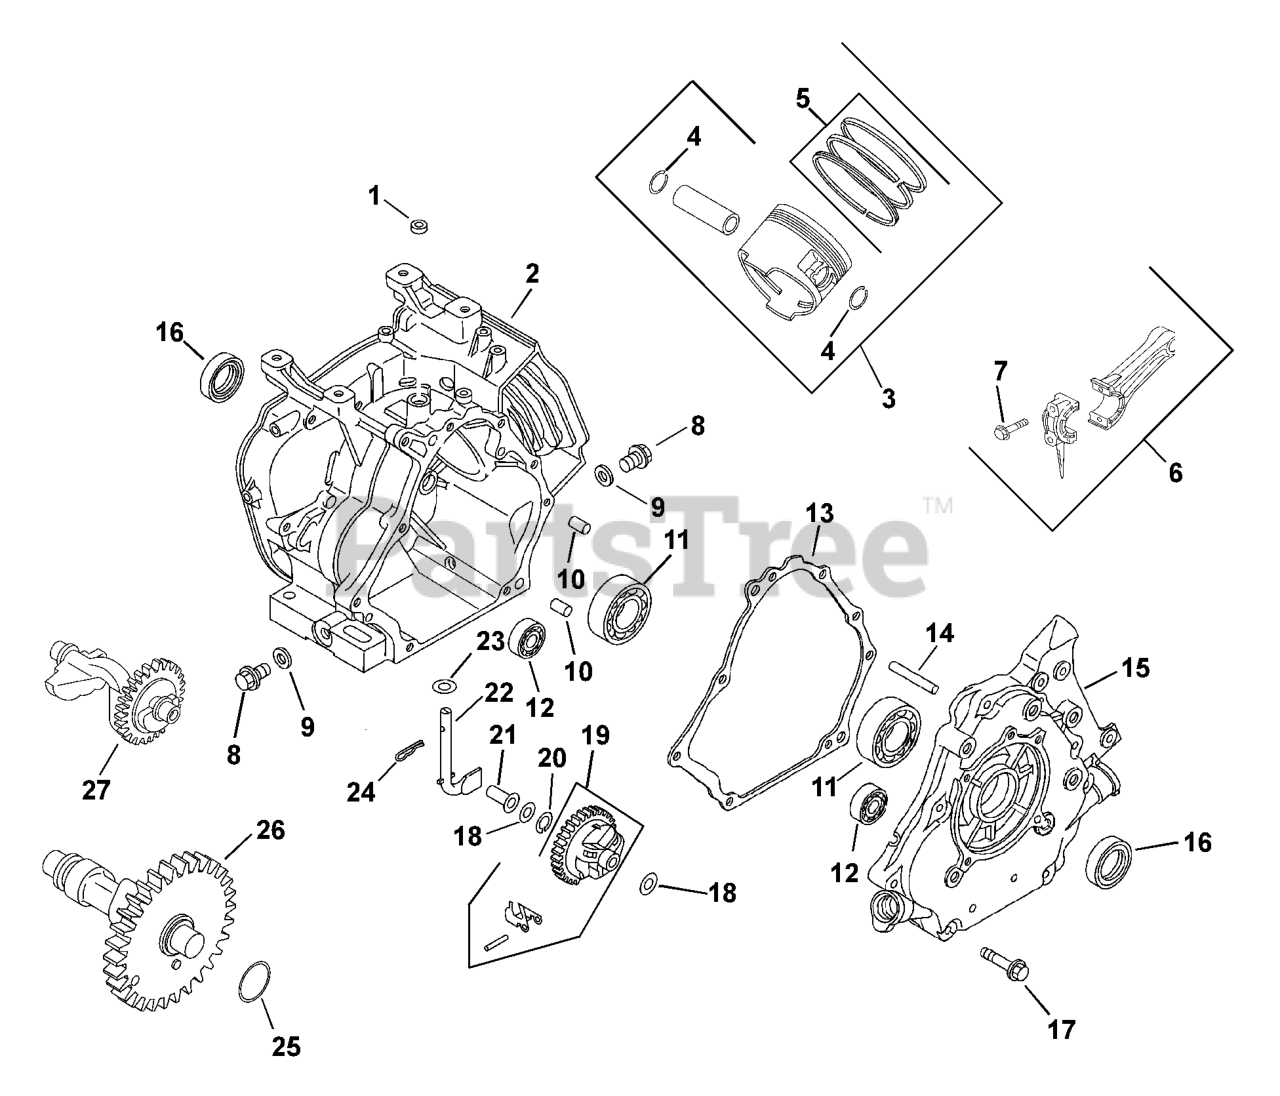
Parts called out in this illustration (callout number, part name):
1	OIL SEAL-GOVERNOR SHAFT
2	CRANKCASE - DISCONTINUED
3	KIT, PISTON W/RING SET (STD)
3	PISTON W/RING SET (+.25)
3	PISTON /WITH RING SET (+.50)
4	RING, RETAINER
5	RING SET (STD)
5	RING SET (.25)
5	RING SET (.50)
6	CONNECTING ROD
7	BOLT, CONN ROD
8	PLUG, DRAIN
9	GASKET, PLUG
10	PIN, DOWEL
11	BEARING, G.R.
13	GASKET, C.P.
14	SHAFT, GOVERNOR
15	CLOSURE PLATE
16	OIL SEAL, G.R.
17	SCREW, FLANGE
19	GOVERNOR GEAR ASSEMBLY
20	SNAP RING
22	SHAFT, GOVERNOR CROSS
27	BALANCE SHAFT
